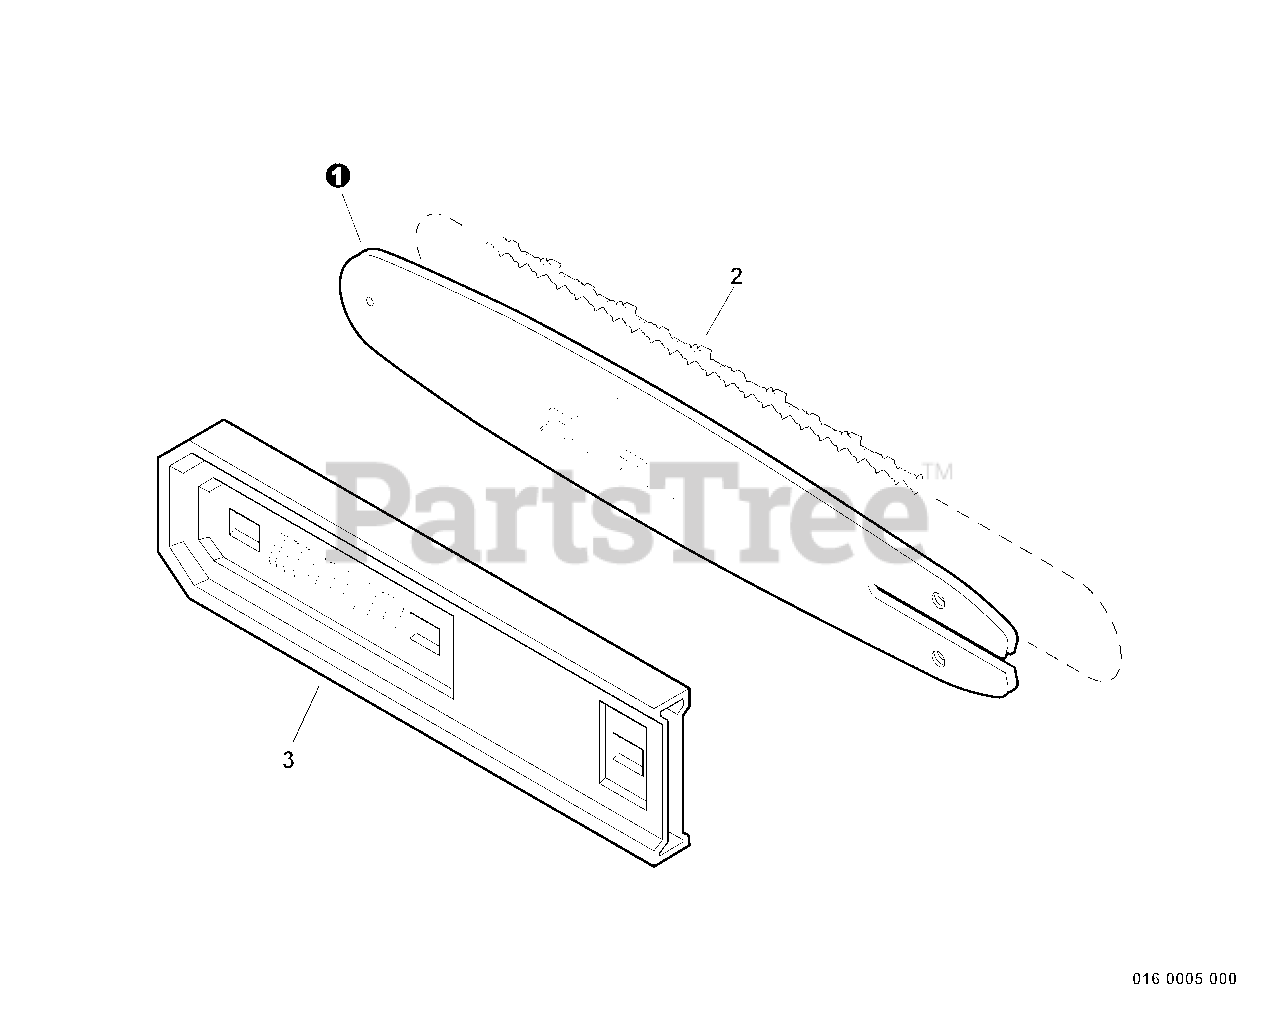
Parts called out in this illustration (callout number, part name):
1	GUIDE BAR, 12" 0.050" GA
2	SAW CHAIN 12" 0.050" GA
3	SCABBARD 12"
